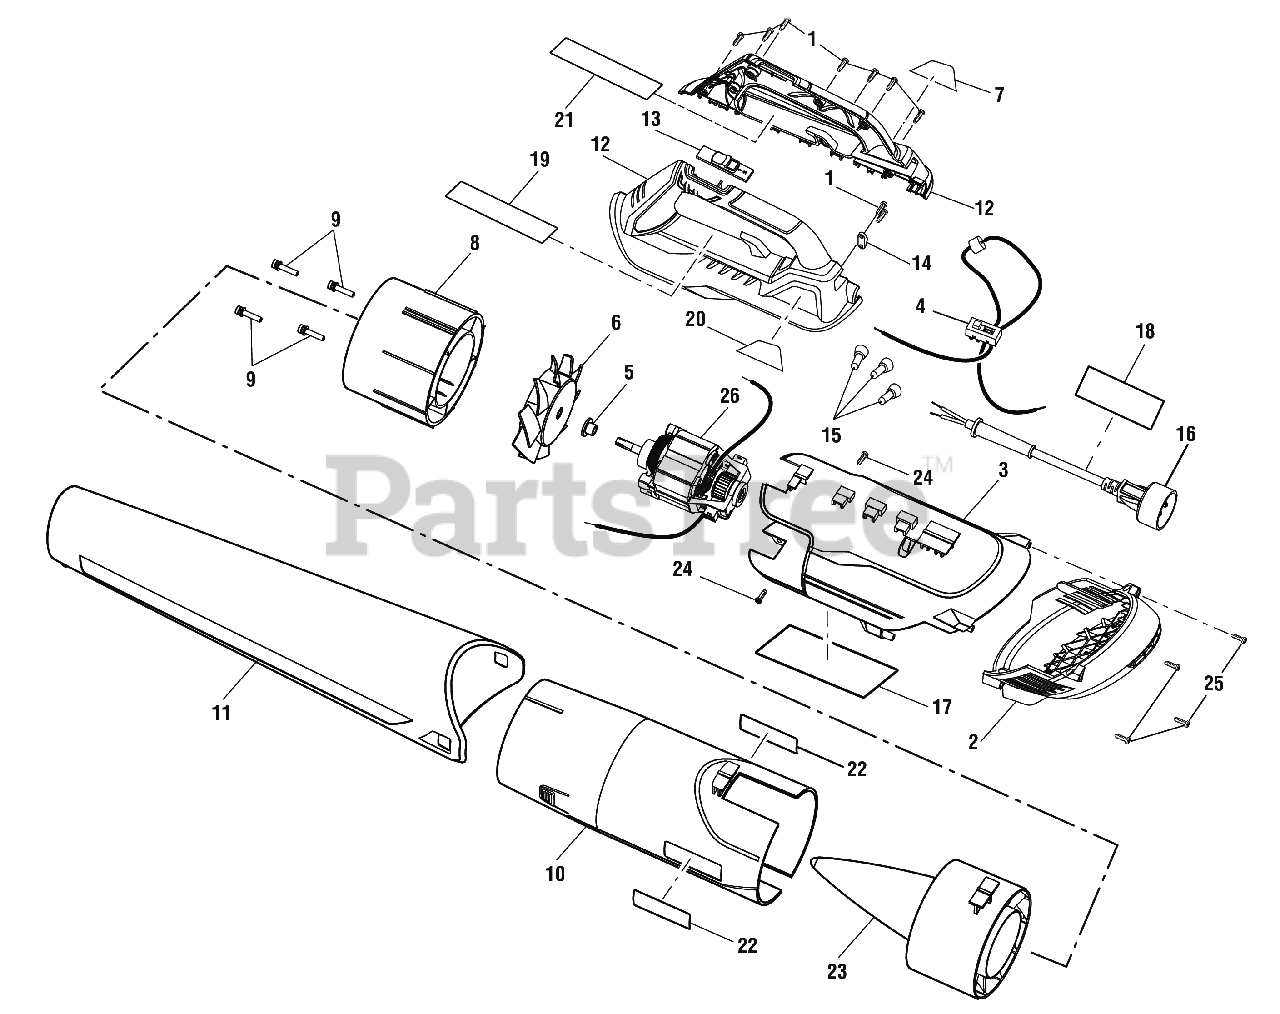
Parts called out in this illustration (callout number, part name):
1	Screw (M4 x 14 mm, T15 Torx Pan Hd.))
2	Inlet Guard
3	Housing Assembly
4	Switch and Fuse Assembly
6	Fan w/Insert Nut
7	8 Amp Label (Right)
8	Motor Housing Assembly
9	Screw w/Washers (M5 x 25 mm, T25 Torx Cap Hd.)
10	Outlet Housing Assembly
11	Blower Tube
12	Handle Assembly
13	Switch Trigger
14	Cord Clamp
15	Wire Connector (Closed End)
16	Power Cord Assembly
17	Data Label (RY42102)
18	Warning Label (Fr/Sp)
19	Icon Warning Label
20	8 Amp Label (Left)
21	Warning Label
22	Logo Label
23	Tail Cone
24	Screw (M4 x 16 mm, T15 Torx Pan Hd.)
25	Screw (M4 x 20 mm, T20 Torx Pan Hd.)
26	Motor Assembly
